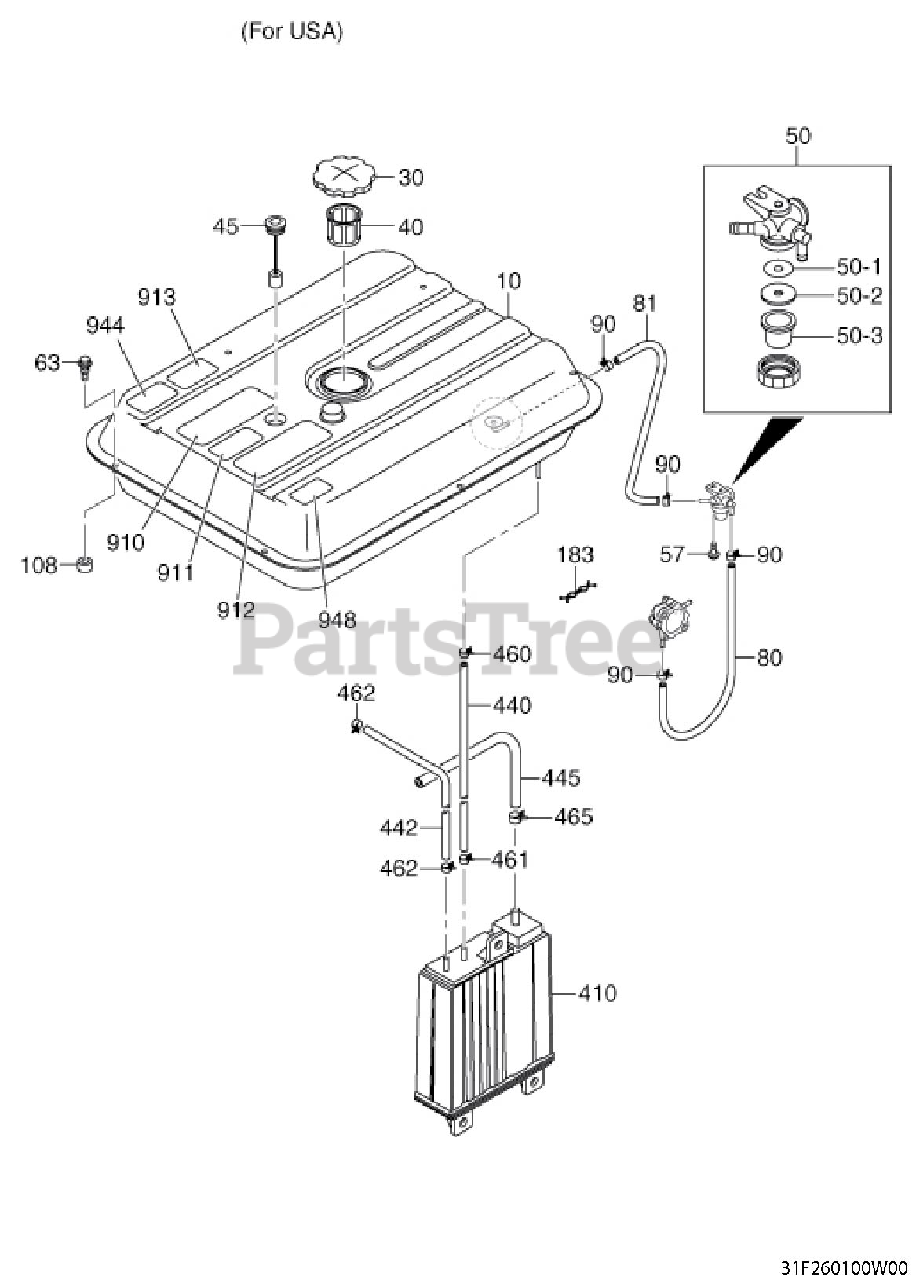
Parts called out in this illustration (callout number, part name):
30	FUEL TANK CAP AY
40	FUEL FILTER
50	FUEL STRAINER AY
80	RUBBER PIPE
81	RUBBER PIPE
90	HOSE CLAMP
410	CANISTER AY
440	RUBBER PIPE
442	RUBBER PIPE
445	RUBBER PIPE
460	HOSE CLAMP
461	HOSE CLAMP
462	HOSE CLAMP
465	HOSE CLAMP
910	LABEL (WARNING)
911	LABEL (CO GAS)
912	LABEL (CAUTION)
913	LABEL (WARNING)
944	LABEL (LEVEL CAUTION)
948	LABEL (SYMBOL-TANK)
